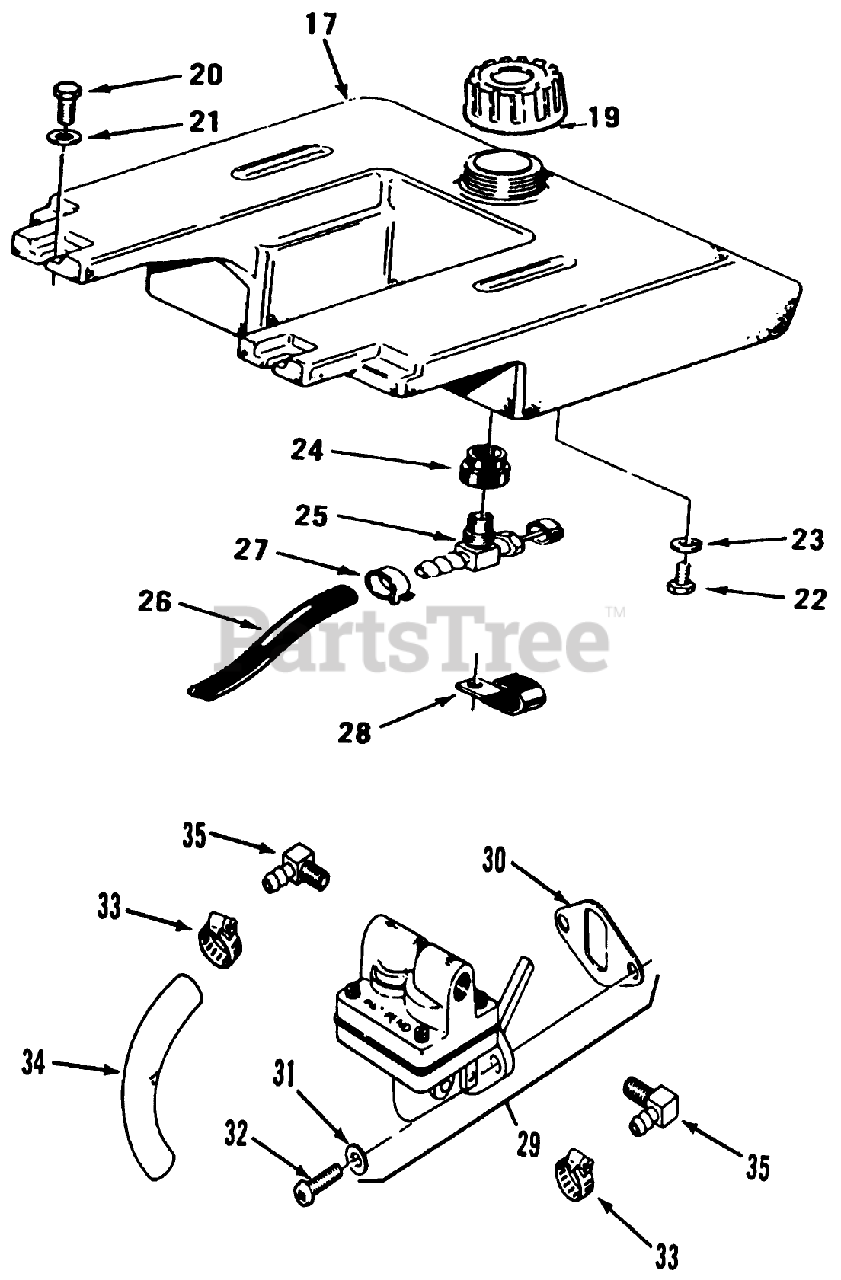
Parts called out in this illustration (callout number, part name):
17	TANK-FUEL
18	GAS CAP ASM
25	VALVE-FUEL
29	KOHLER 47-599-08
30	KOHLER 25-041-05
31	KOHLER X-159-2
32	KOHLER X-174-2
33	KOHLER X-426-9
34	KOHLER 25-353-01
35	KOHLER 25-155-02
